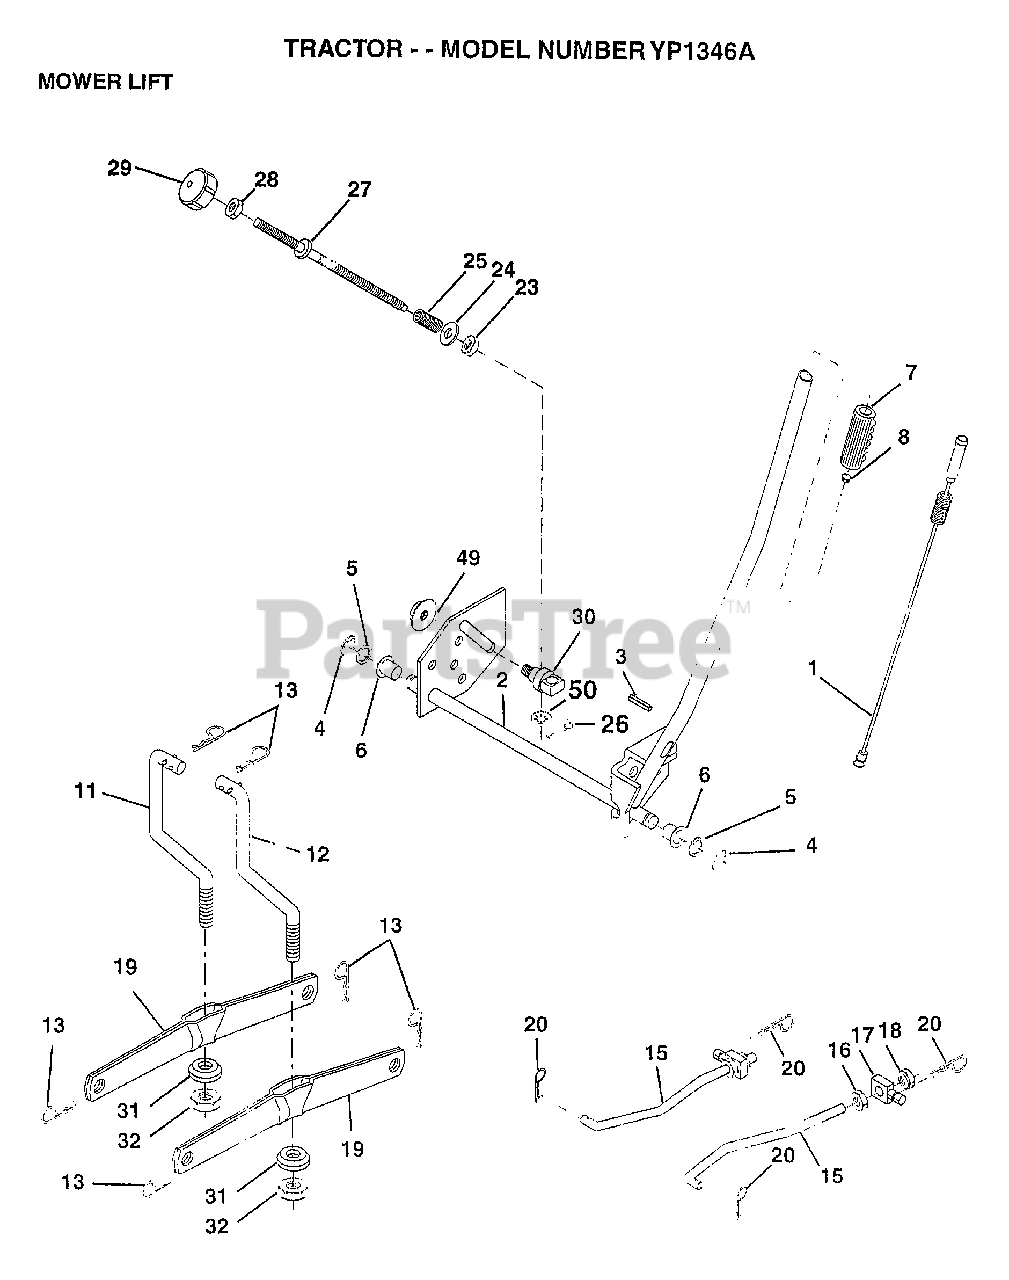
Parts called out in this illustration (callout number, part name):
1	WIRE ASM W.SPRING
2	SHAFT ASM LIFT
3	PIN-GROOVE LT
5	WASHER
6	NYLON BEARING
7	GRIP HANDLE
15	LINK.FRONT
16	NUT
17	TRUNION
18	NUT.LK.W/WSH.1/2.
19	ARM SUSP REAR
20	RETAINER.SPRING
23	NUT T
24	WASHER
25	SPRING T
28	NUT
29	KNOB INF 3/8-16
30	TRUNNION
31	BEARING PVT LH
32	NUT.CROWNLOCK.3/8
49	NUT.HXFLG.LOCK.
50	NUT PUSH M
